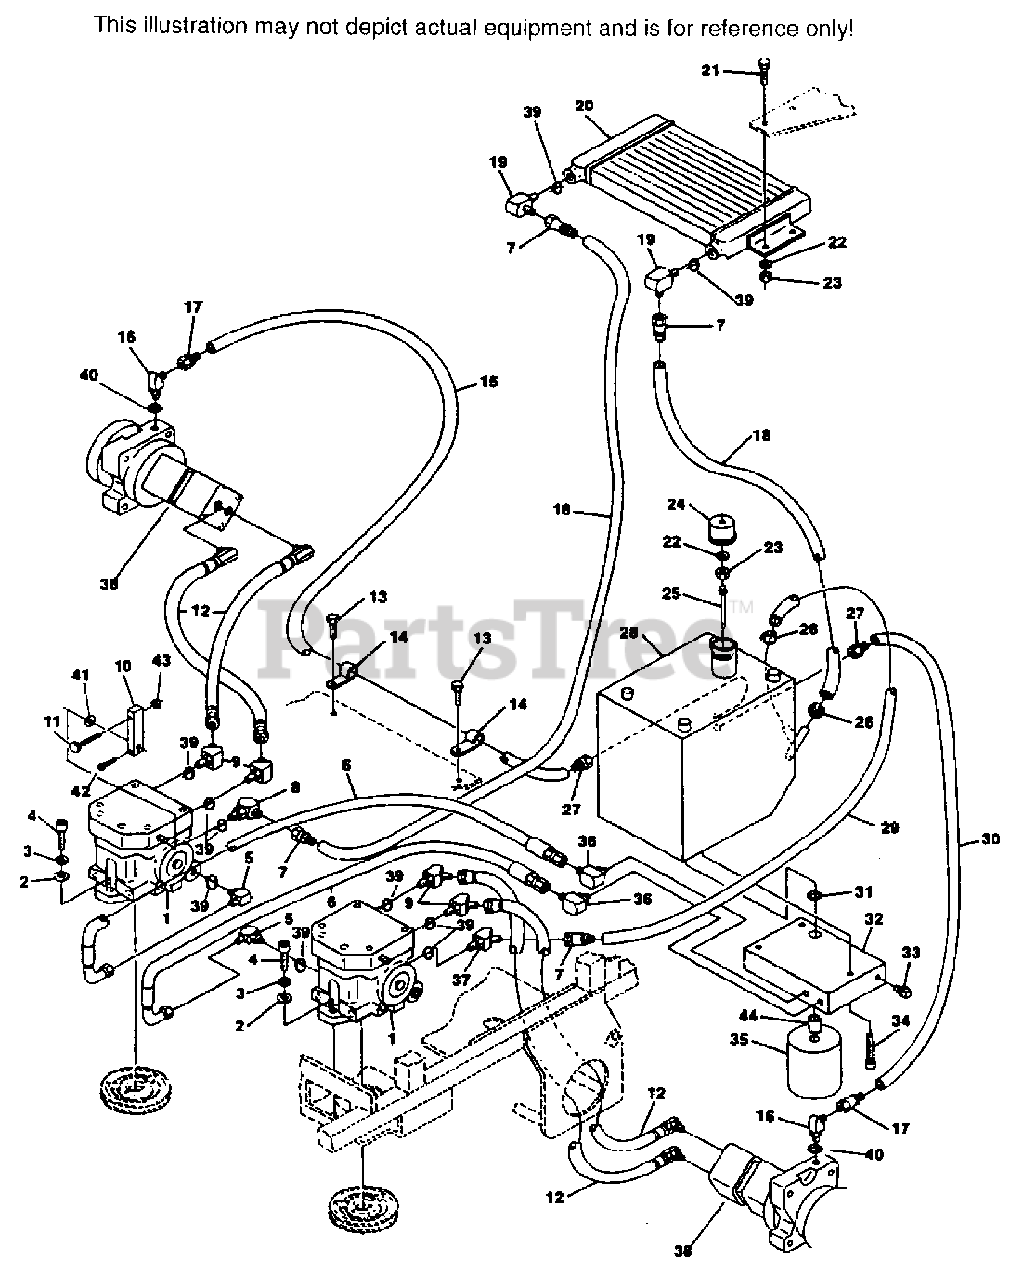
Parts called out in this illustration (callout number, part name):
1	PUMP, SUNDSTRAND
2	FLAT WASHER(.500 X .937 X .105)
4	CAPSCREW, SOCKET HD., 5/16-18 X 3/4
5	ELBOW 90 DEG., 1-1/16-12 JIC TO 3/4-16 "O"
6	HOSE ASSEMBLY, PUMP SUCTION
7	COUPLING, 7/8-14 SAE FLARE TO 5/8 ID HOSE
8	ELBOW 90 DEG., 7/8-14 JIC TO 3/4-16 "O"
9	ELBOW 45 DEG., 7/16-20 JIC TO 3/4-16 "O"
10	LEVER
11	THUMBSCREW
12	HOSE ASSEMBLY, PUMP TO MOTOR
14	HOSE CLAMP
15	HOSE, 1/4" ID - 44" LONG
16	ELBOW 45 DEG., 7/16-20 JIC TO 7/16-20 "O"
17	COUPLING, 7/8-14 SAE FLARE TO 1/4 ID HOSE
18	HOSE, 5/8" ID - 18-1/2" LONG
19	90 DEG ELBOW 7/8-14 JIC TO 3/4-16 "O"
20	OIL COOLER
24	CAP, OIL RESERVOIR
25	DIP STICK
26	HOSE CLAMP
27	COUPLING, 1/4 NPT TO 1/4 ID HOSE
28	OIL RESERVOIR
29	HOSE, 5/8" ID - 16" LONG
30	HOSE, 1/4" ID - 10" LONG
31	"O" RING, 1/8 X 1 ID
32	OIL MANIFOLD
33	PIPE PLUG, 1/2 NPT
34	CAPSCREW, SOCKET HD., 3/8-16 X 2
35	OIL FILTER
36	ELBOW 90 DEG.
37	ELBOW 45 DEG., 7/8-14 JIC TO 3/4-16 "O"
38	WHITE MOTOR
39	"O" RING, 3/32 X 5/8 ID
40	"O" RING 1/16 X 3/8 ID
41	WAVE WASHER
42	CAPSCREW
44	NIPPLE, OIL FILTER
